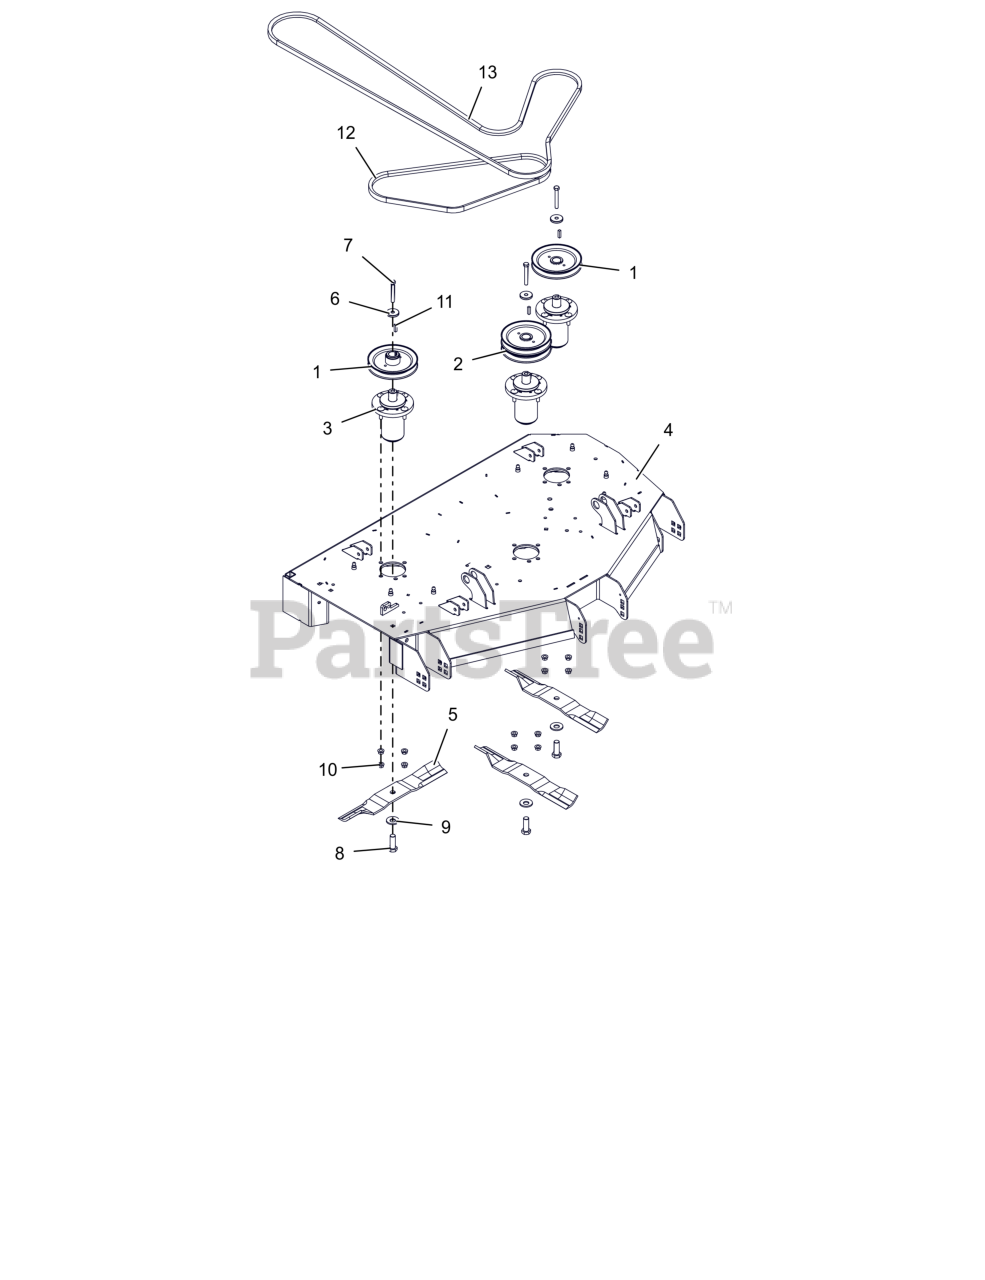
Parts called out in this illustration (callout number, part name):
1	PULLEY, SINGLE-1"ID X 6" OD
2	PULLEY, DOUBLE
3	ASM, MAINT FREE ALUM SPINDLE
4	KIT, DECK-44 W/DECALS 7GA XF3 RED
5	BLADE, 16.19" MOWER (HI-LIFT)
6	RETAINER, SHEAVE
7	BLT, HEX .38-16X2.75 G8 ZCC
8	BLT, HEX .62-18X1.75 G8 ZCC
9	WSHR-BLVL .669X1.535X.138
10	NUT-LK-CTR-FLG .375-16 GF ZCC
11	KEY, SQ .25X.25X1.00 RC 40-50
12	V-BELT, B-COGGED
13	V-BELT, HB RAW EDGE EPDM
